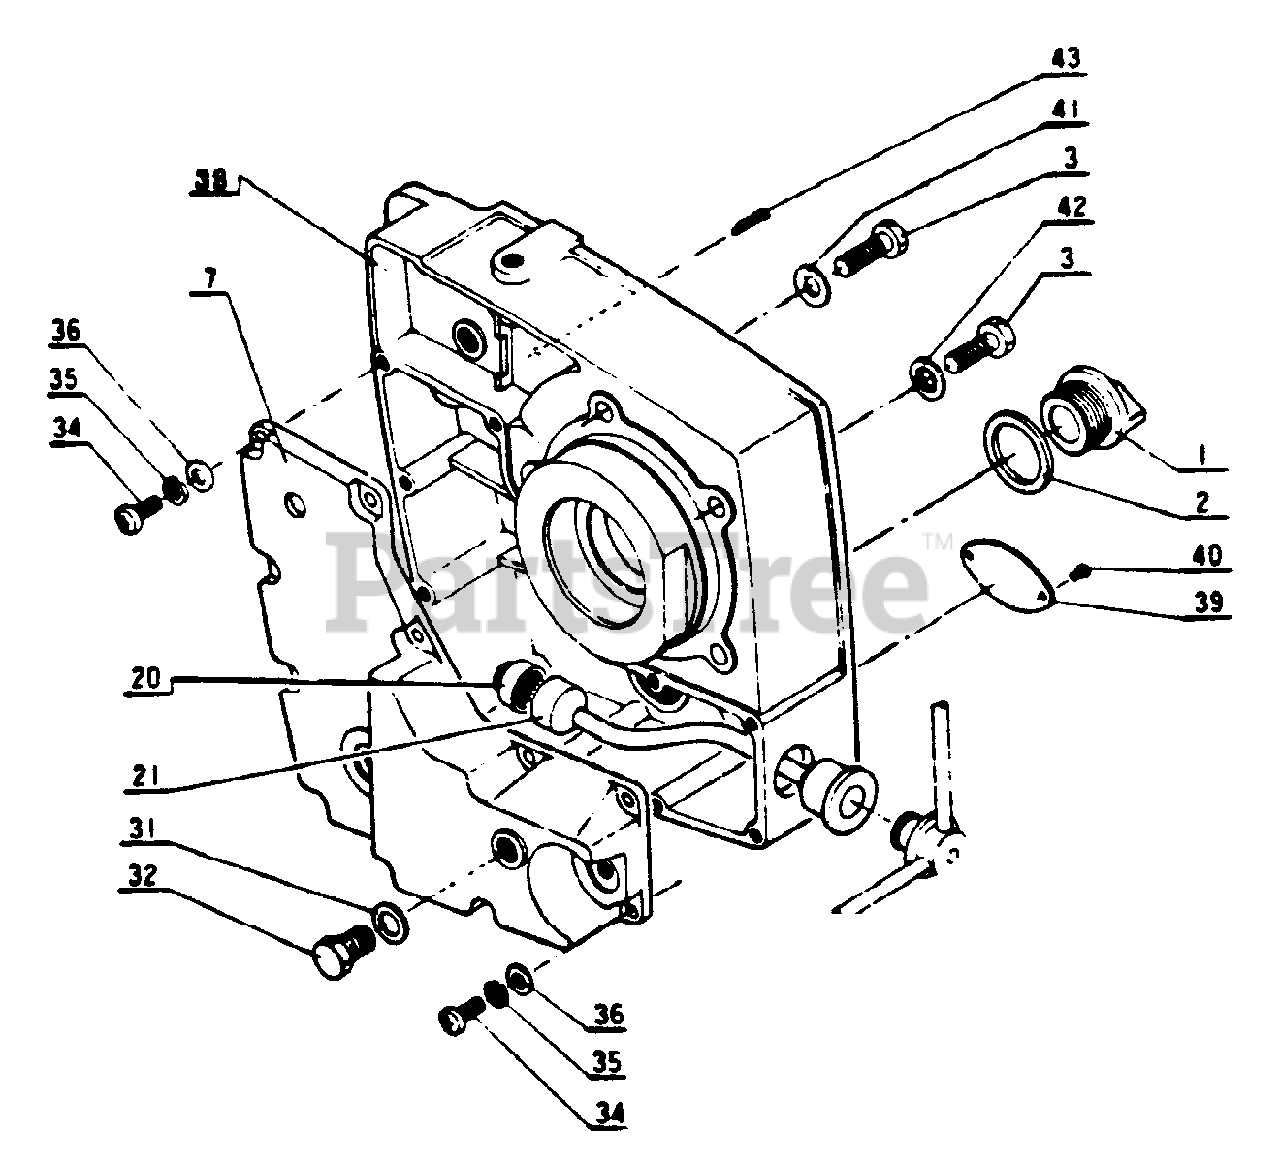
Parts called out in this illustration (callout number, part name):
1	CAP
2	GASKET, CAP
3	BOLT
7	TANK, OIL
20	FILTER, OIL
21	PIPE, OIL - INNER
31	GASKET
32	BOLT - 8X12
34	SCREW - 4X12
35	LOCKWASHER - 4
36	WASHER - 4
38	CRANKCASE
39	PLATE, MODEL
40	RIVET
41	WASHER
42	WASHER
43	PIN, SPLIT -- 2X15
